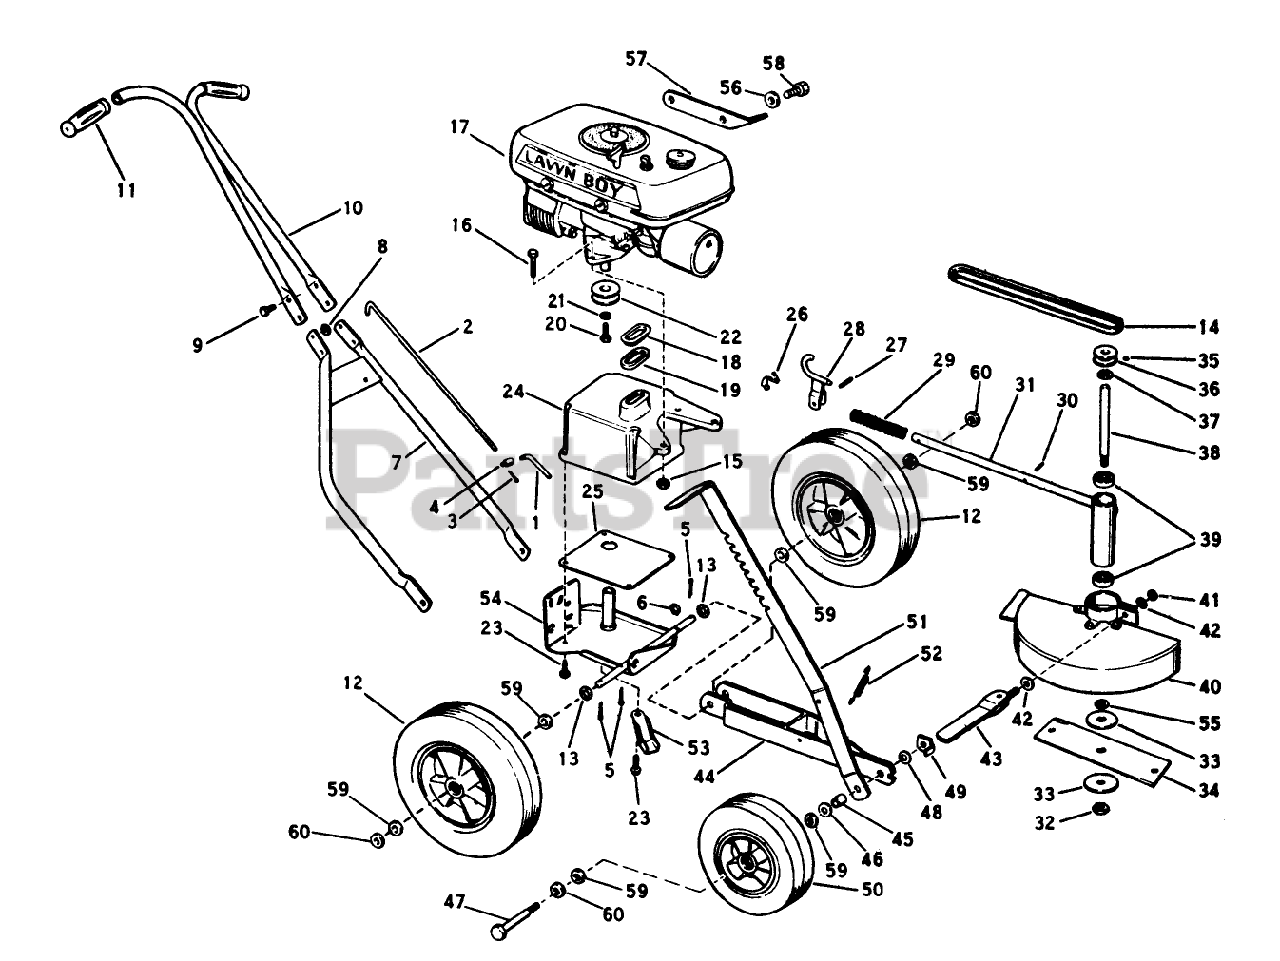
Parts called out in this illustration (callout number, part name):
8	STOP NUT
11	HANDLE GRIP
19	GASKET S
21	WASHER, LOCK
34	Blade-9"
44	Wheel Bracket and Spacer Assy.
48	WASHER, LOCK
